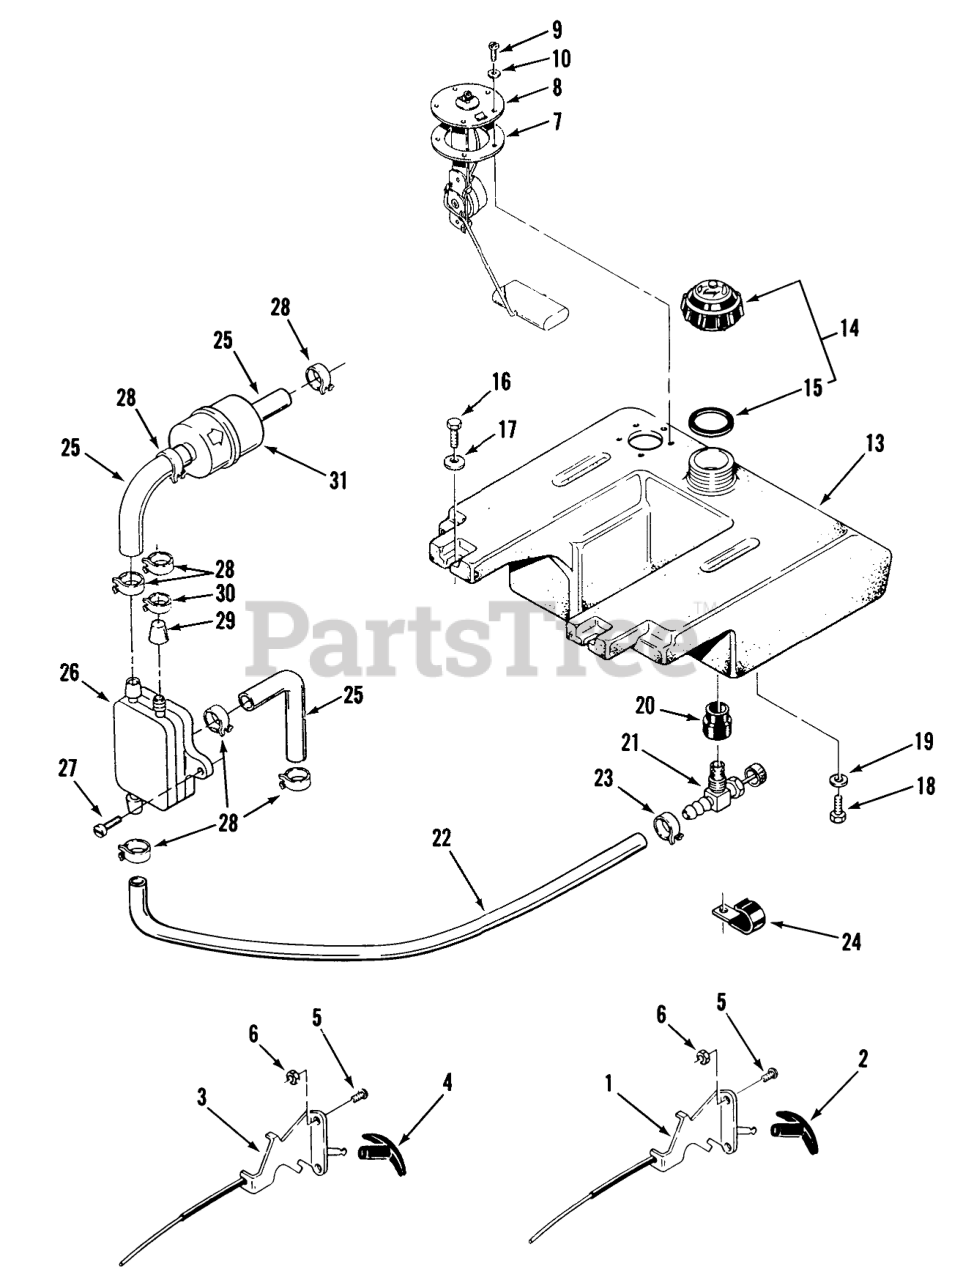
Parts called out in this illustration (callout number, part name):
1	CONTROL-THROTTLE
2	KNOB-THROTTLE
3	CONTROL-CHOKE
4	KNOB-CHOKE
5	SCRW-PHC
6	Nut
7	GASKET-SENDER, FUEL
8	SENDER-FUEL LEVEL
9	Screw
10	Lockwasher
13	Fuel Tank (includes items 20 & 21)
14	Fuel Cap (includes item 15)
15	GASKET-GAS CAP
16	Bolt
17	Washer
18	Bolt
19	Lockwasher
20	BUSHING
21	VALVE-FUEL
22	Line-Fuel 53"
23	Clamp
24	Clamp
24	CLAMP
25	Hose
26	Fuel Pump
27	Screw
28	Clamp
29	Cap
30	Clamp
31	Filter-Fuel
